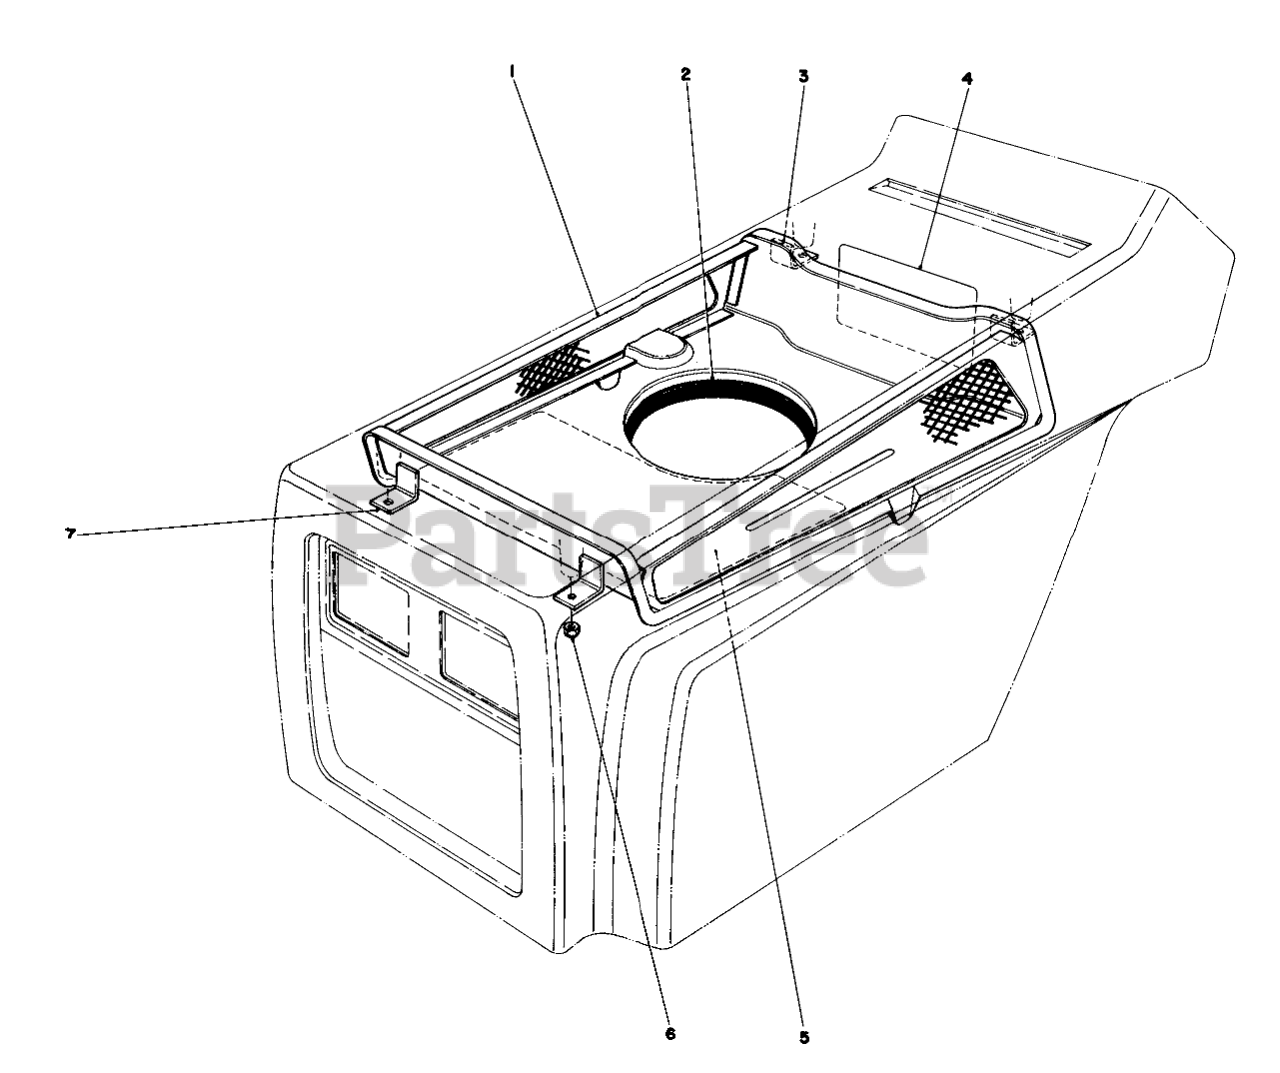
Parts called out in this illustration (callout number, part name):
1	Duct Hood
2	Seal Engine
3	Bracket Rear Duct Support
4	Decal-Belt Change
5	Decal Service
6	NUT-LOCK, CONE
7	Bracket Duct Support
